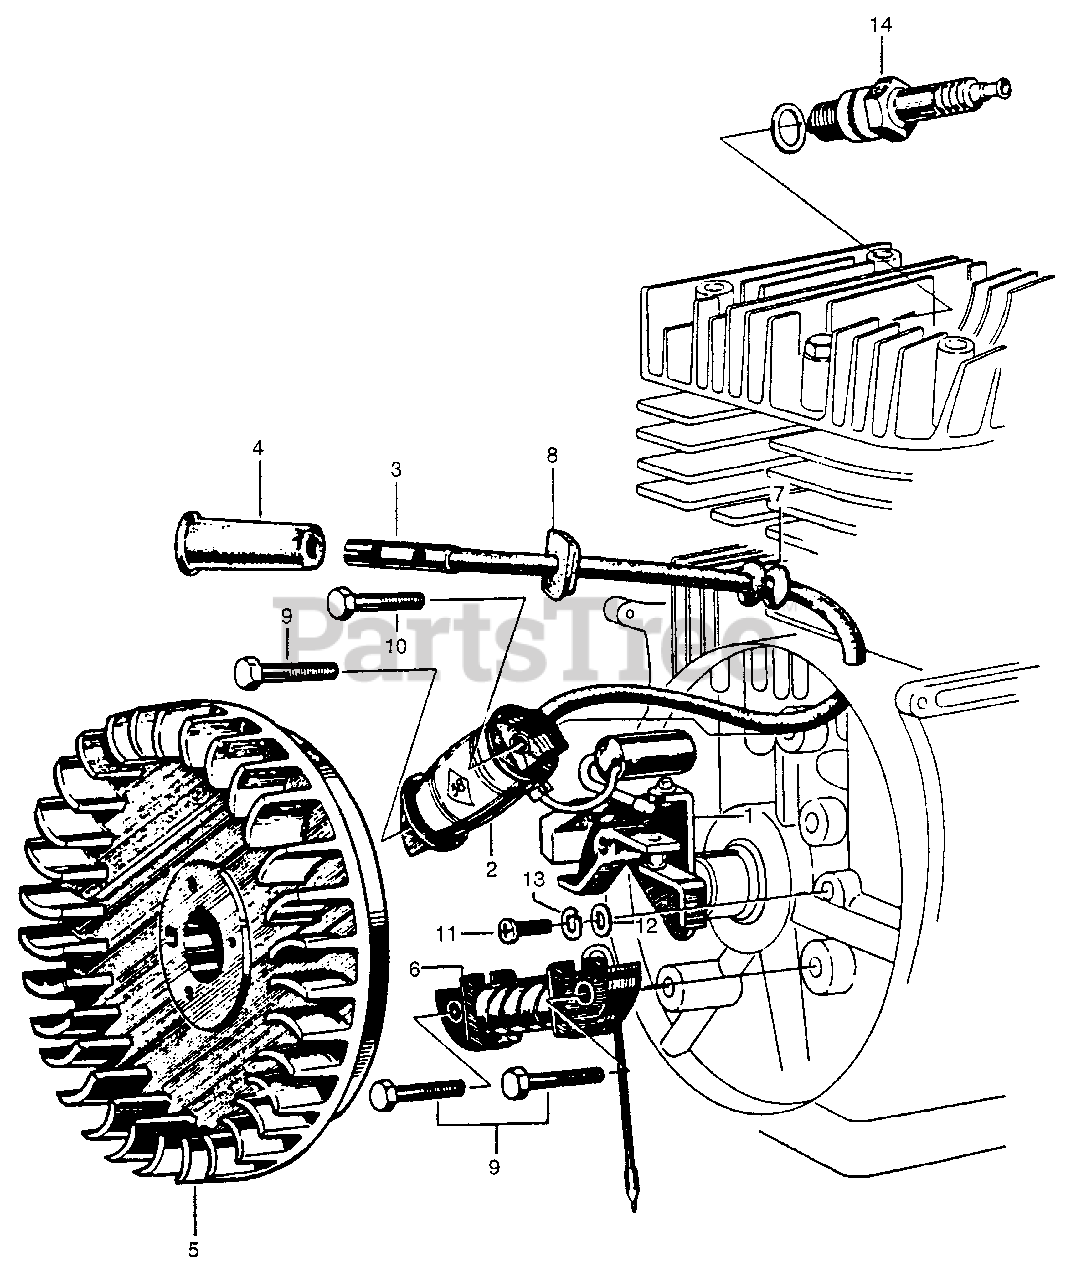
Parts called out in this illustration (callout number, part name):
1	CONDENSER, BREAKER (NOT AVAILABLE)
1	CONDENSER, BREAKER
2	COIL, IGNITION
2	COIL, IGNITION (NOT AVAILABLE)
3	TERMINAL, IGNITION
4	CAP, IGNITION TERMINAL
4	CAP, IGNITION TERMINAL (NOT AVAILABLE)
5	FLYWHEEL, MAGNETO (NOT AVAILABLE)
6	COIL, LAMP (NOT AVAILABLE)
7	GROMMET, WIRE
7	GROMMET, WIRE (NOT AVAILABLE)
8	GROMMET, IGNITION WIRE
9	BOLT, HEX. (6X32)
10	BOLT, HEX. (6X35)
11	BOLT, RECESSED (5X14) (NOT AVAILABLE)
12	WASHER, PLAIN (5MM)
13	WASHER, SPRING (5MM)
14	SPARK PLUG (B6HS) (NGK)
